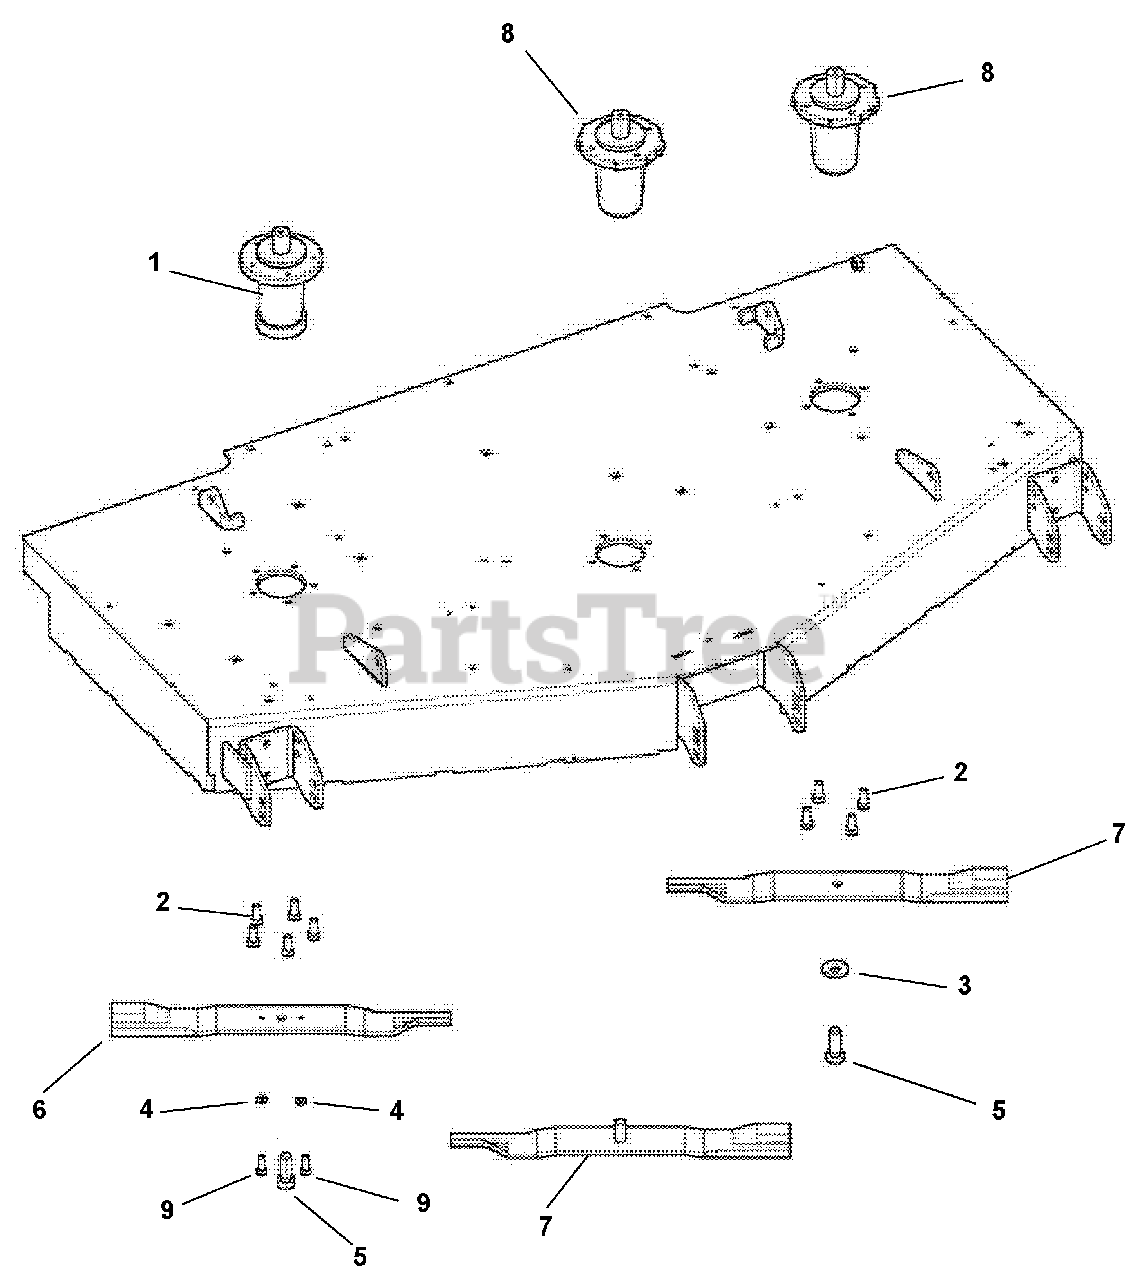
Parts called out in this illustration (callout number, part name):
1	Spindle Assembly
2	Bolt, Hex .375-16 x 1
3	Washer, Belleville .63 x 1.625 x .14
4	Lock Washer, Spring Regular
5	Bolt, Hex .62-18 x 1.75
6	Blade, 20.83" Mower (Counterclockwise Rotation)
7	Blade, 20.83"
8	Housing, Spindle (G5000)
9	Bolt, Hex .31-18 x 1.00 Grade 5
